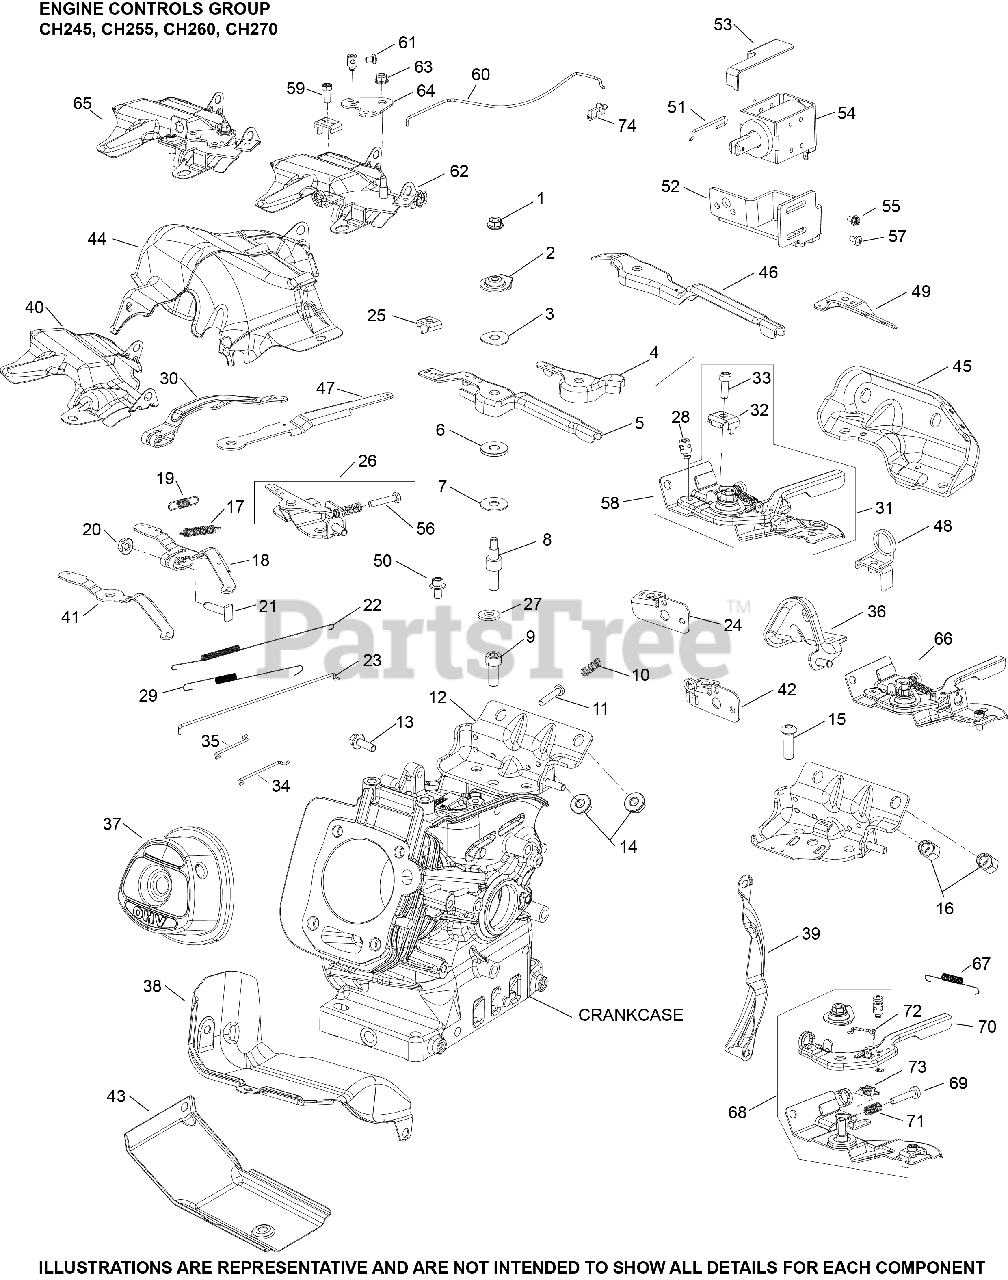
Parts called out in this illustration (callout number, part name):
19	SPRING, GOVERNOR
23	LINKAGE, GOVERNOR - (#1807905S)
28	KIT, CABLE CLAMP
29	SPRING, LINKAGE
30	KIT, GOVERNOR LEVER
31	VARIABLE SPEED CONTROL ASSEMBLY
32	CLAMP, CABLE
